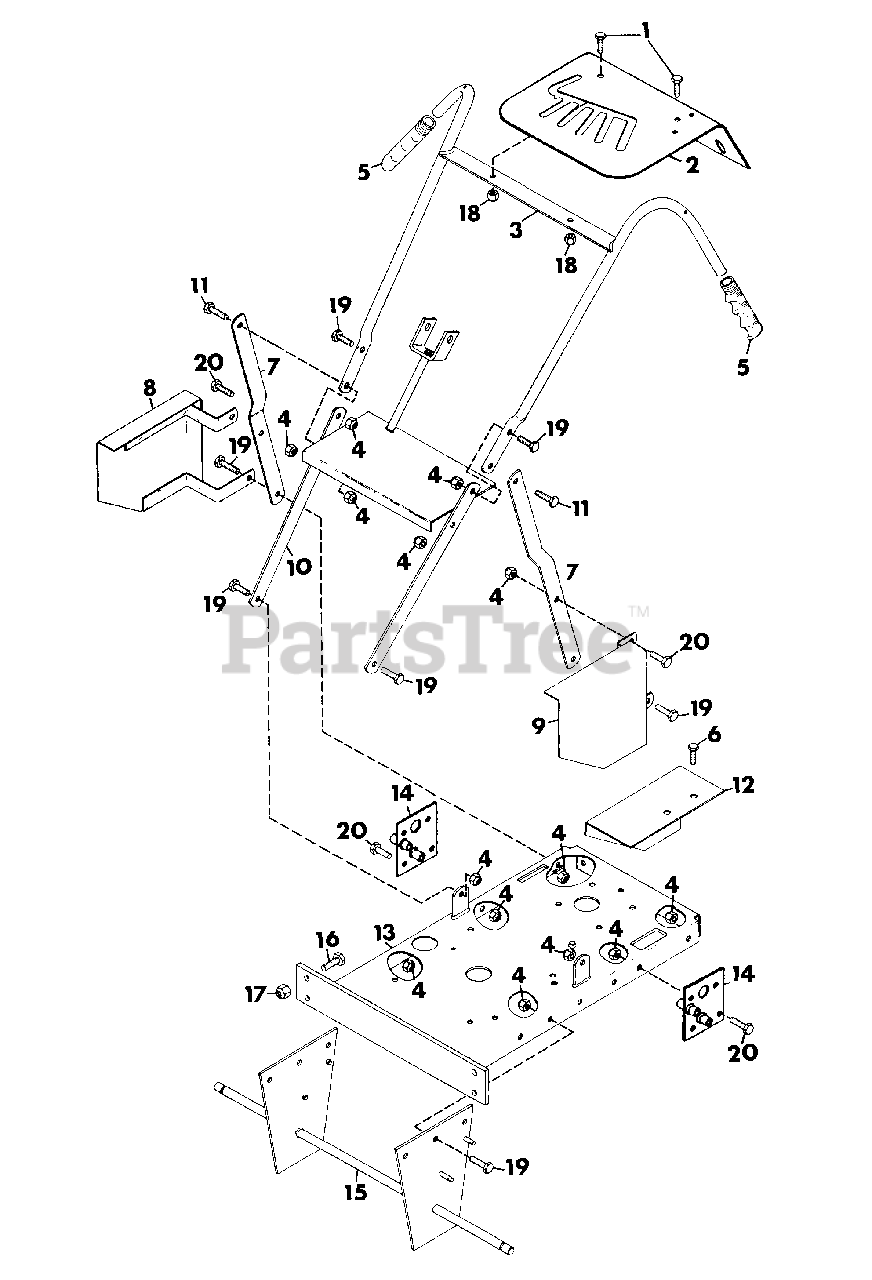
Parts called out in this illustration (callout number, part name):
1	BOLT, HEX 5/16-18X1.00
2	PLATE, INSTRUCTION
3	WELDMENT, HANDLEBAR
4	NUT, LOCK 3/8-16
5	GRIP, HAND
6	BOLT, SELF-TAPPING 5/16-18X.50
7	BRACE, HANDLEBAR SUPPORT
8	WELDMENT, BELT GUARD R.H.
9	WELDMENT, BELT GUARD L.H.
10	WELDMENT, HANDLE BAR SUPPORT
11	BOLT, HEX 3/8-16X1.25
12	GUARD, TRANSMISSION CHAIN
13	WELDMENT, FRAME
14	WELDMENT, BEARING SUPPORT L.H.
15	WELDMENT, AXLE
16	BOLT, HEX 1/2-13X1.50
17	NUT, LOCK 1/2-13
18	NUT, LOCK 5/16-18
19	BOLT, HEX 3/8-16X1.00
20	BOLT, HEX 3/8-16X.75
